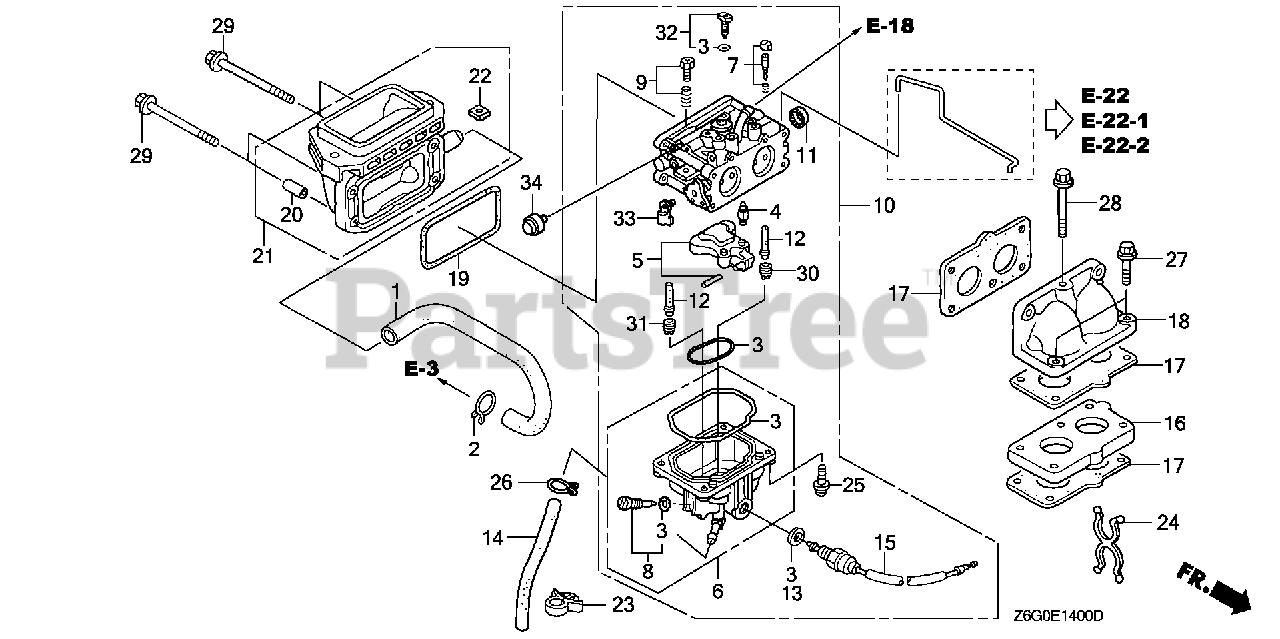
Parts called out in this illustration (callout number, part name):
1	TUBE, BREATHER
2	CLIP, BREATHER TUBE
3	GASKET SET
4	VALVE SET, FLOAT
6	CHAMBER SET, FLOAT
7	SCREW SET, PILOT
8	SCREW SET, DRAIN
9	SCREW SET, THROTTLE
10	CARBURETOR ASSY. (BK01A B)
11	CAP, CHOKE DUST
12	NOZZLE, MAIN
13	WASHER, PLAIN
14	TUBE, DRAIN
15	VALVE ASSY., SOLENOID (KEIHIN)
16	INSULATOR, CARBURETOR
17	GASKET, CARBURETOR
18	ELBOW, MANIFOLD
19	GASKET, AIR CLEANER
20	COLLAR A, AIR CLEANER
21	ELBOW, AIR CLEANER
22	NUT, INSERT (6MM)
23	CLIP B, CABLE (9MM BLACK)
24	CLIP, PURSE LOCK
25	SCREW, PAN (4X12)
26	CLIP, TUBE (B8)
27	BOLT, FLANGE (6X30)
28	BOLT, FLANGE (6X65)
29	BOLT, FLANGE (6X90)
30	JET, MAIN (#90)
30	JET, MAIN (#95)
30	JET, MAIN (#100)
31	JET, MAIN (#90)
31	JET, MAIN (#95)
31	JET, MAIN (#100)
32	JET SET, PILOT (#40)
33	ARM, THROTTLE LINKAGE
34	FILTER ASSY., AIR VENT
